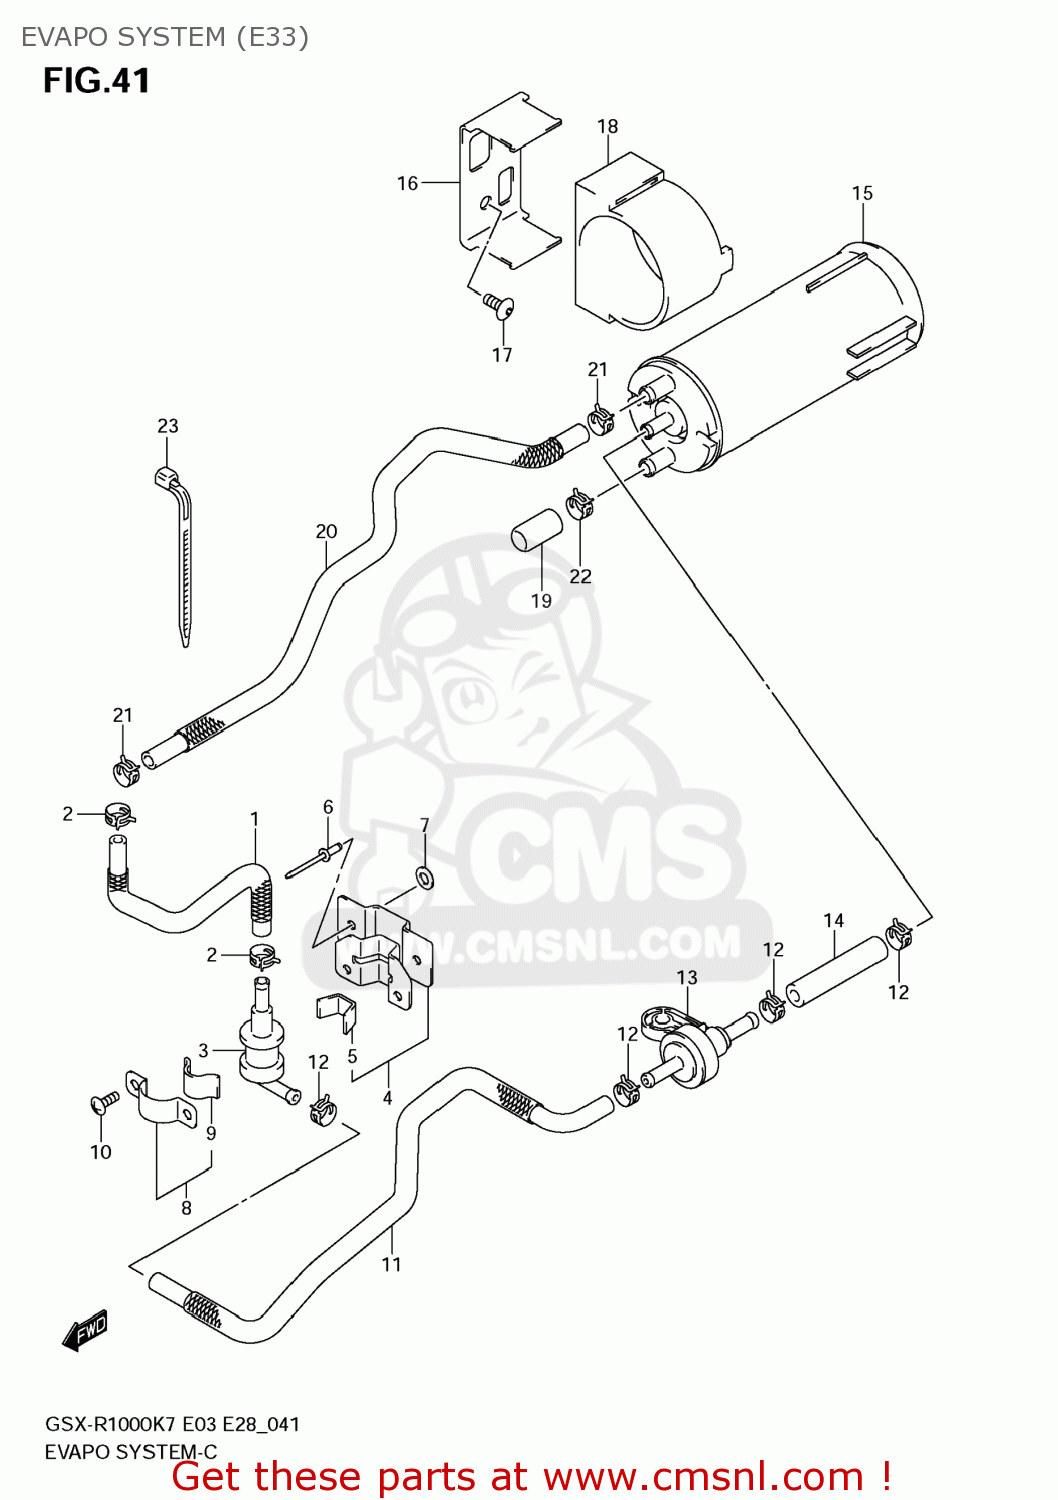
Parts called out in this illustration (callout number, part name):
1	HOSE,TANK & BRT
2	CLIP
3	VALVE,FUEL TANK BREATHER
4	PLATE,BREATHER VALVE
5	CUSHION
6	RIVET
7	WASHER
8	PLATE,FUEL TANK BREATHER NO.2
9	CUSHION
10	SCREW
11	HOSE,BRTHR VALVE & 2 WAY VALVE
12	CLIP
13	VALVE,2 WAY & BREATHER VALVE
14	HOSE(5.4X11.4X600)
15	CANISTER ASSY,CHARCOAL
16	BRACKET,CANISTER
17	SCREW,6X10
18	CUSHION,CANISTER
19	CAP
20	HOSE,CSTR PURGE
21	CLIP
22	CLIP
23	CLAMP(L:100)
